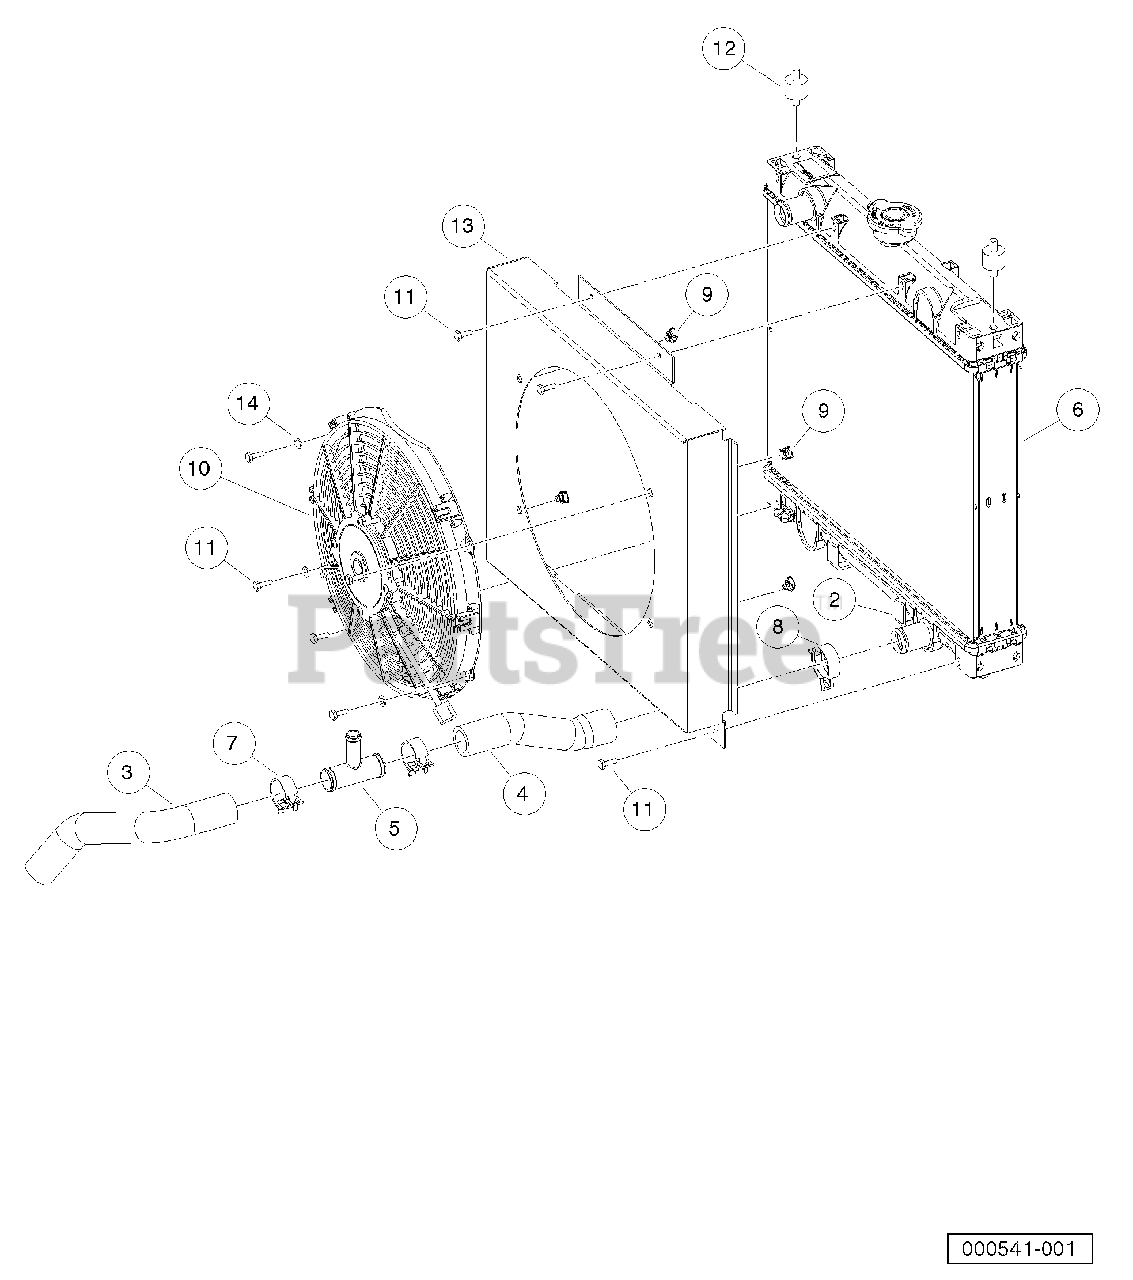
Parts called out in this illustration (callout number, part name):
1	Asm, Radiator
2	Tape, Vinyl Foam 1/8" x 3/4"
3	Hose, Coolant Lower Pipe
4	Hose, Coolant Lower Rad
5	Tee, Coolant Fill
6	Exchanger, Engine Coolant
7	Clamp, Hose, Ctb 35mm
8	Clamp, Hose, Ctb 38mm
9	Nut, Self Retaining
10	Fan, Cooling 12 In Elect
11	Bolt, M6 X 1 X 16 Loctite
12	Isolator, Twin-Stud
13	Shroud, Radiator Fan
14	Washer, M6
